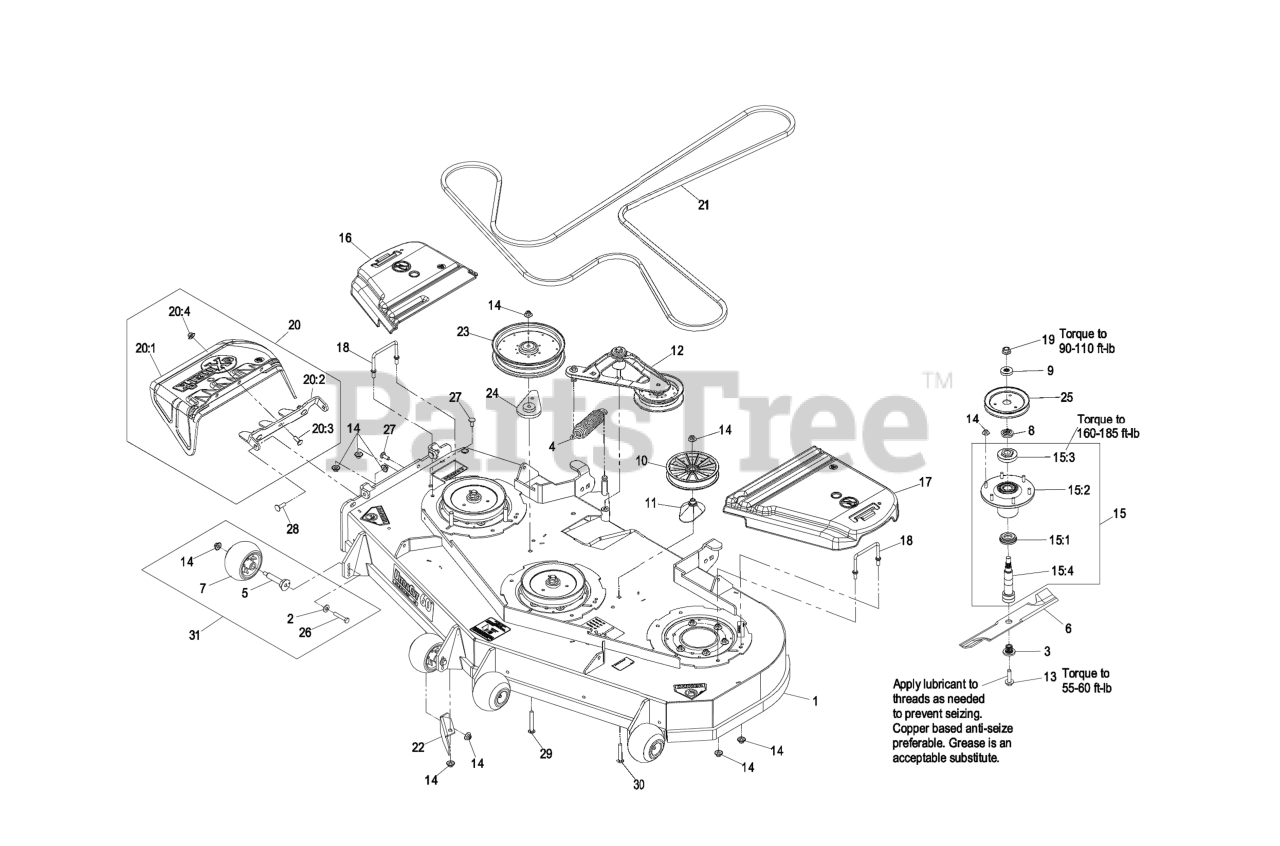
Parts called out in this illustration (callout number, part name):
2	WASHER-BELLEVILLE
3	BUSHING,SPLINED
7	ROLLER-SCALP, ANTI
8	SPACER,SPLINED STEPPED
9	SPACER,SPLINED
10	PULLEY,IDLER 6"
11	SPACER-PULLEY
13	SCREW,SEMS 1/2-20 X 2.19
14	Nut-Nyloc 3/8-16 Flg
15	ASM,SPINDLE HOUSING
15:1	GUARD,BOTTOM
15:2	ASM,CUTTER HOUSING
15:3	NUT, SPINDLE 7/8-14
15:4	SPINDLE,DOUBLE SPLINE
16	COVER-BELT, RH
17	COVER-BELT, LH
18	WIREFORM-COVER
19	NUT-FLANGE, CENTERLOCK
20	ASM,DISCHARGE CHUTE
20:1	CHUTE,DISCHARGE
20:2	BRACKET,DISCHARGE CHUTE
20:3	SCREW-CARR
20:4	Nut-Nyloc 3/8-16 Flg
21	BELT,V-5V-198.75
22	BAFFLE,DISCHARGE 52/60
23	PULLEY-IDLER
24	SPACER-IDLER
25	SHEAVE,BLADE DRIVE 7.25
26	SCREW-HH
27	SCREW-CARR
28	Bolt-Carriage 3/8-16 X 1 1/4
29	SCREW-CARR
30	SCREW-CARR
32	Asm, Deck Complete 606
